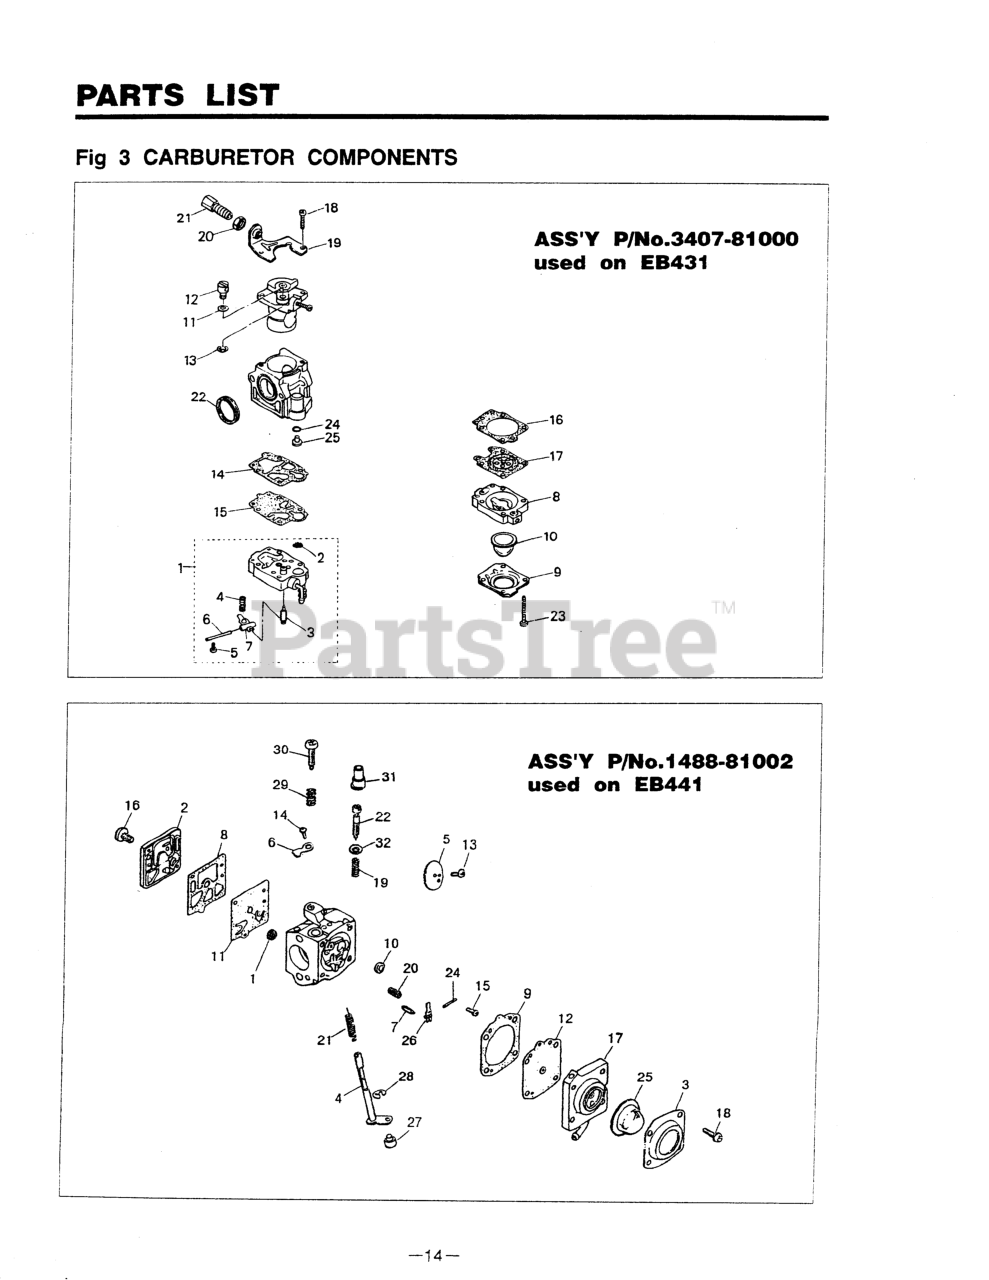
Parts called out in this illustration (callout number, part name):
2	COVER, PUMP
3	COVER, PUMP
4	SHAFT ASSEMBLY
5	VALVE, THROTTLE
6	THROTTLE STOP
7	VALVE, INLET
8	KIT ONLY
9	KIT ONLY
10	PLUG, WELSH
11	KIT ONLY
16	SCREW (RPLS 1491-81130)
17	BODY ASSY (RPLS 1491-81490)
18	SCREW (REPLACES 1491-81350)
20	KIT ONLY
21	SPRING
22	NEEDLE (NLA)
24	PIN, METERING LEVER
25	PUMP, PRIMER
26	KIT ONLY
29	SPRING, IDLE
NI	REBUILD KIT, EB430/440
NI	EB430/40 DIA/GASK KIT
